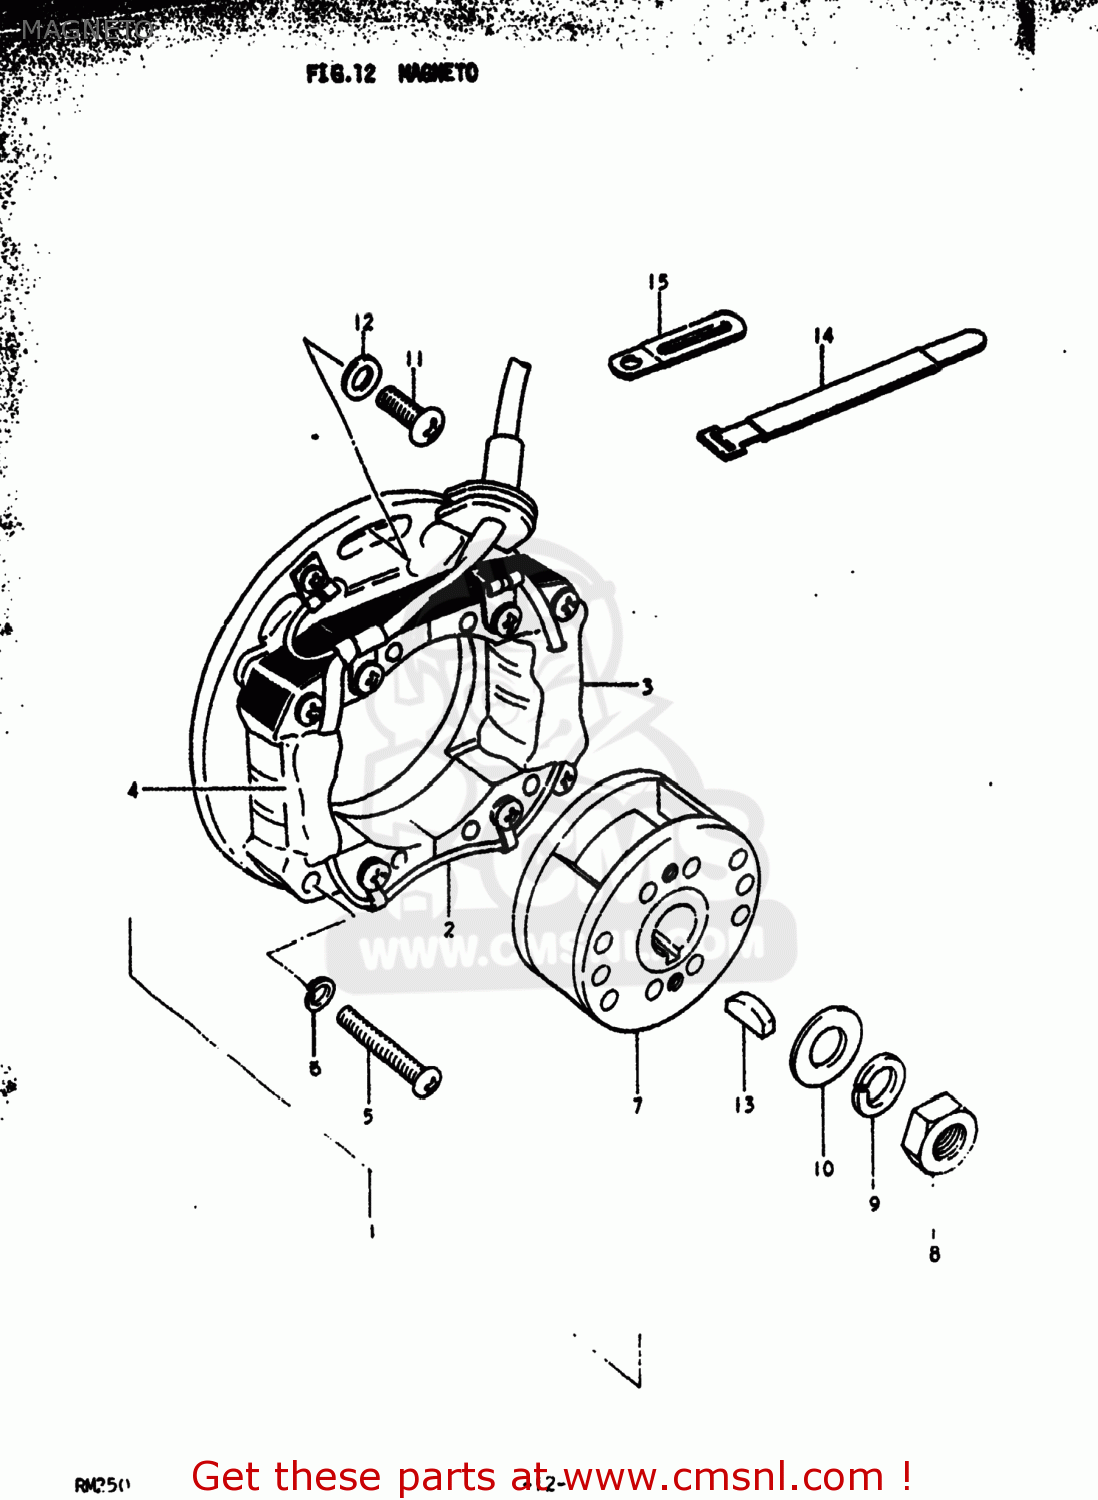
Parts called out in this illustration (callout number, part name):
1	MAGNETO ASSEMBLY
2	STATOR ASSEMBLY
3	COIL,PRIMARY
4	COIL,PULSER
5	SCREW
6	LOCK WASHER
7	ROTOR ASSEMBLY
8	NUT (10MM)
9	LOCK WASHER
10	WASHER
11	SCREW
12	WASHER
13	KEY 4MM
14	CLAMP
15	CLAMP
